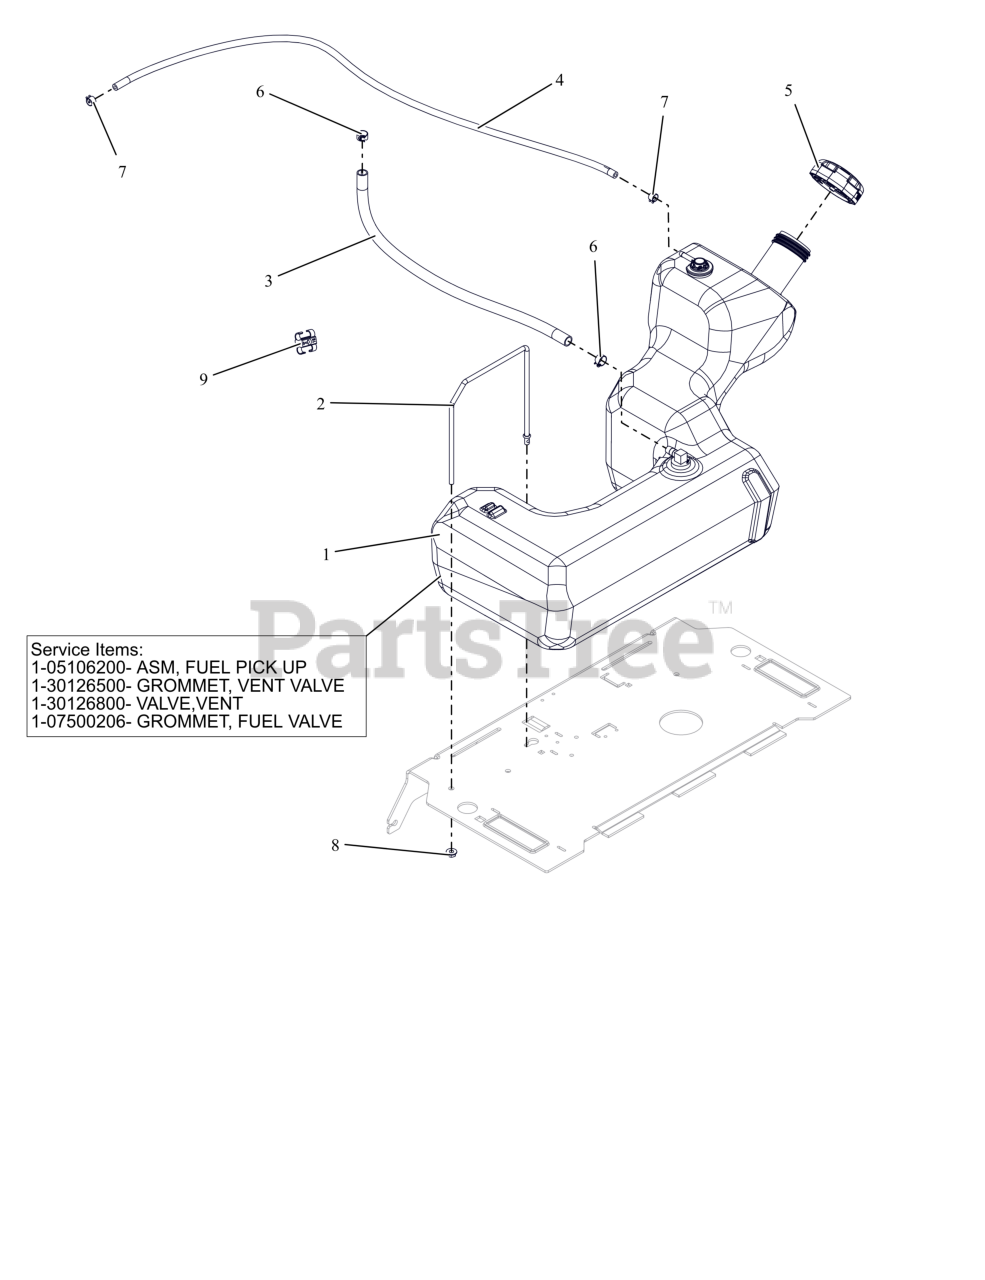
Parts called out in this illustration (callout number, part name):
1	ASM, FUEL TANK - IKON 23
1	ASM, IKON FUEL PICK-UP
1	GROMMET, VENT VALVE
1	VALVE, VENT
1	BSHG-FLG .375X1.062X.625 NITR
2	STRAP, TANK HOLD DOWN
3	1 INCH OF HOSE, .25 LOW-PERM BULK GAS
4	HOSE, .188 30R7 BULK
5	CAP-FUEL- 2.25 RATCHET INLET V
6	CLAMP, FUEL LINE
7	CLAMP-HOSE, SPRING .188
8	NUT-LK-CTR-FLG .25-20 ZC120
9	CLIP, T, .38-.50
